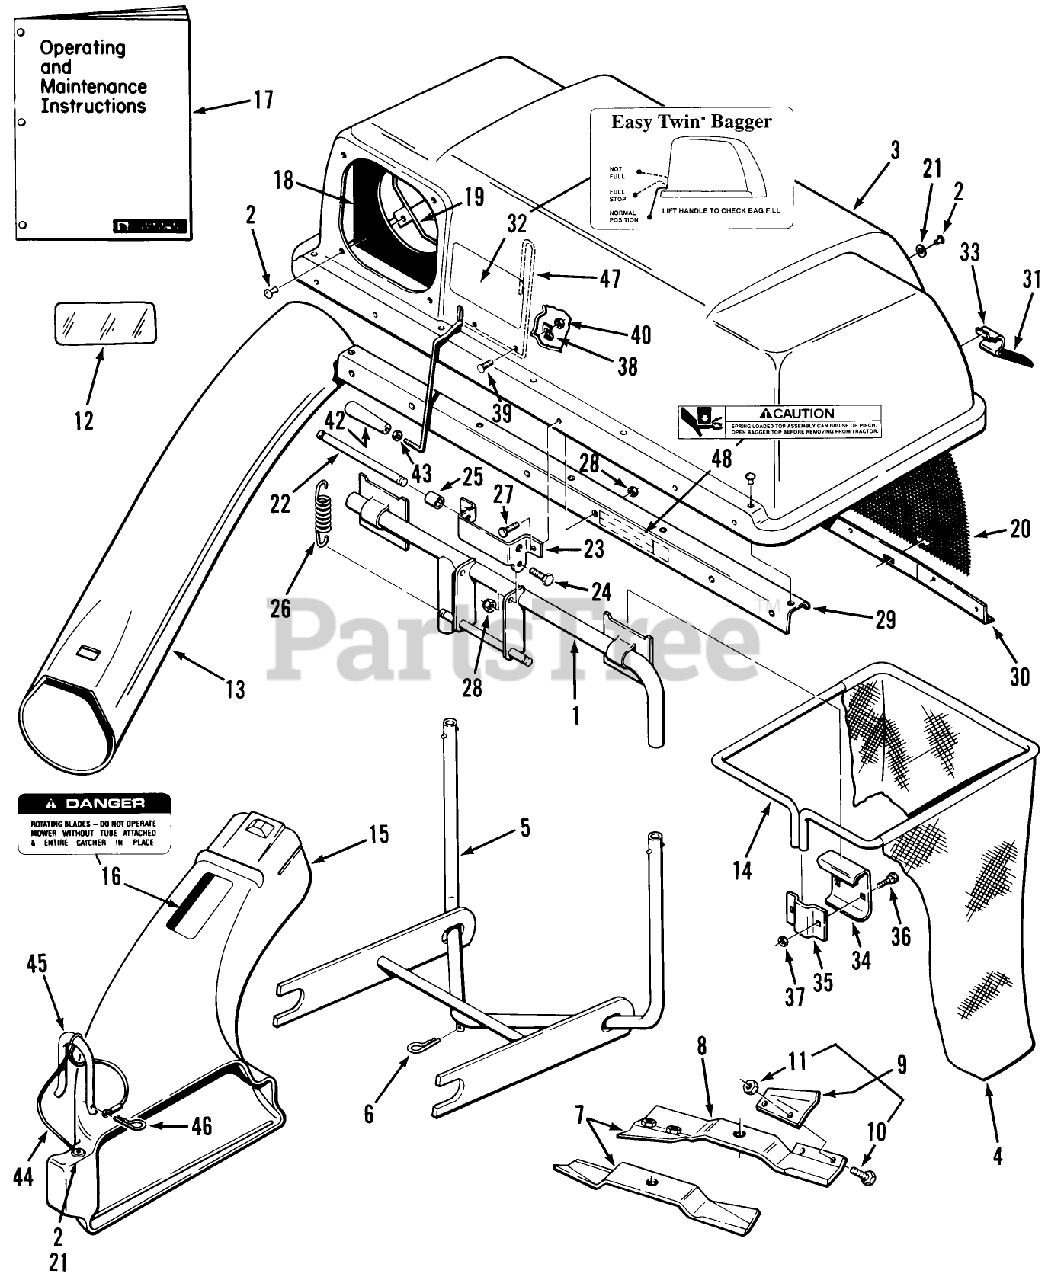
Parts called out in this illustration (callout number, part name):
2	RIVET-BLIND
5	ASS'Y-QUICK ATTAC *B
6	Hairpin
7	KIT-BLADE (SERVICE)
8	ASS'Y-HI LIFT BLADE
9	S/A 37 LIFT TAB KIT
10	BOLT 5/16-18X5/8
11	NUT-HEX
12	DECAL-OVERLAY
13	CHUTE-BAGGER (L)
16	DECAL-DANGER
17	Operating and Maintenance Instructions
19	CLAMP-SEAL
20	SCREEN-BAGGER
22	PIN-SPRING
26	SPRING-EXTENSION
42	HANDLE-TAPERED
44	LANYARD-ELBOW LATCH
45	LATCH-ELBOW
46	Hairpin Cotter
47	FEELER-FILL, BAG
